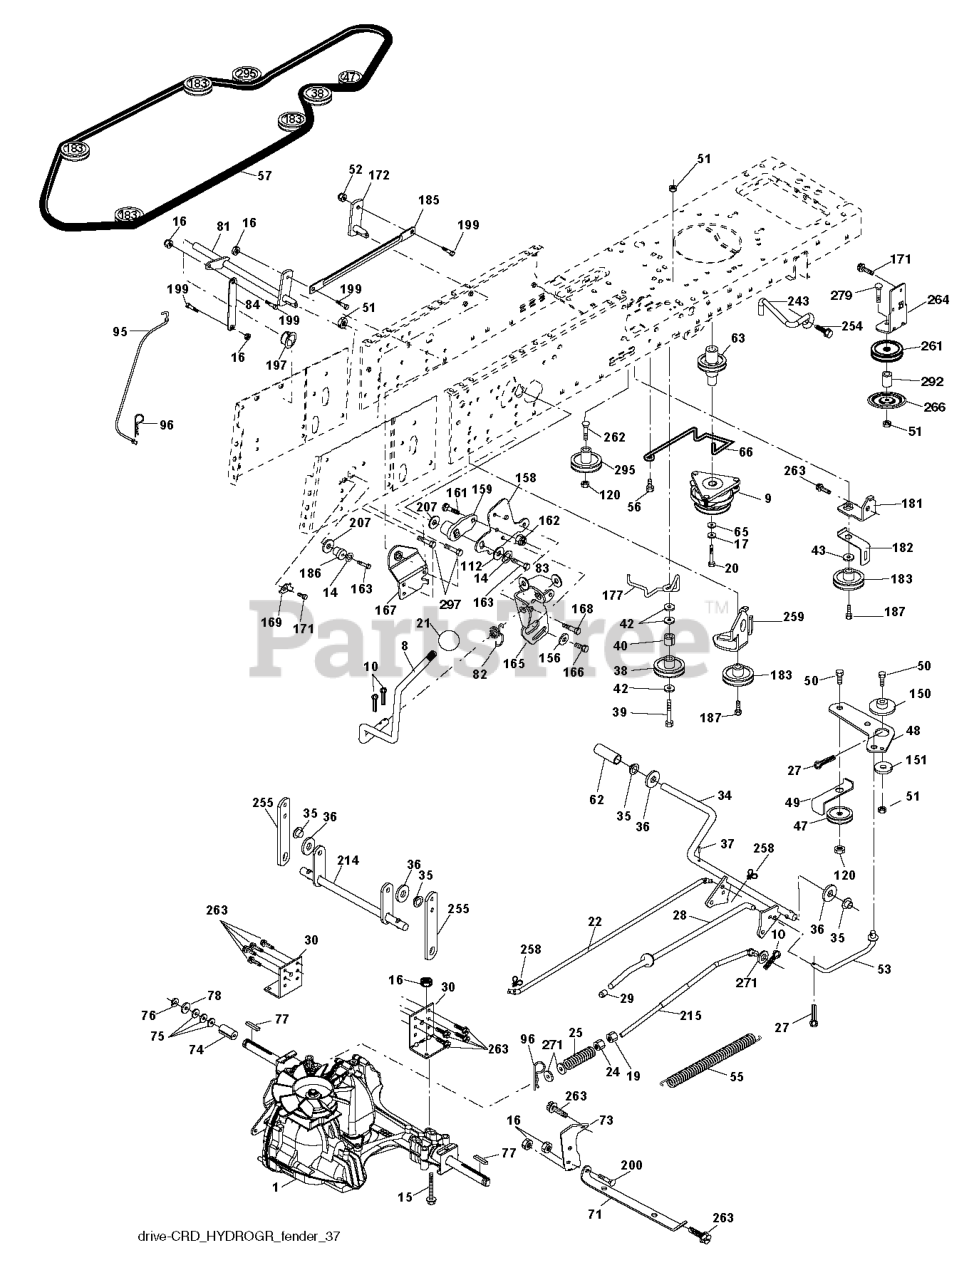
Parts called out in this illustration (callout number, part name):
8	ROD SHIFT FENDER ADJUST LT
9	CLUTCH.ELECTRIC.OGURA.EURO.
10	PIN COTTER
14	LOCKWASHER
15	BOLT HEX 5/16-18 GR 5
16	NUT.71038.31-18.HEX.NYLOCK
19	NUT
20	BOLT HEX 7/16-20X4-1/4"
21	KNOB.DUCKHEAD.1/2
22	ROD
24	NUT
25	SPRING BRAKE ROD
27	COTTER PIN
28	ROD, PARKING BRAKE
29	PLUNGER CAP
30	BRKT, TRNSXLE MNT 20"
34	SHAFT, FOOT PEDAL
35	BEARING.NYLON
36	WASHER LT
37	DRIVE PIN
38	PULLEY.FLAT
42	WASHER
43	WASHER T
47	IDLER PULLEY
48	BELLCRANK, CLUTCH
49	RETAIN BELT
50	BOLT.3/8-16X1.50
52	LOCKNUT
53	LINK.CLUTCH.7.66.2005
55	SPRING, RETURN LT
56	SCREW.3/8-16
57	V-BELT 113"
62	PEDAL COVER T
63	PULLEY.ENGINE.CVX.LT
65	LOCKWASHER
66	KEEPER BELT ENGINE
71	STRAP TORQUE LH HYDRO
73	STRAP TORQUE RH HYDRO
74	SPACER AXLE
77	SQUARE KEY
81	ASM.CROSS.SHAFT.REAR.CRD.0510
82	SHIFT SPRING
83	WASHER
84	LINK.PNT.TRANSAXLE.0510.CRD
95	LINK
96	RETAINER M
112	WASHER LT
120	NUT LOCK FLG 3/8-16 UNC
150	BUSHING.BELLCRANK.GRD.DR
151	WASHER 12/32X2X10GA
156	WASHER.SRRTD.5/16
158	BRACKET.SHIFT.MOUNT
159	RB HUB.SHIFT
161	BOLT
162	NUT.CROWNLOCK.1/4
163	BOLT
165	BRACKET.PIVOT.LEVER
166	CAPSCREW.HXHD.FLG.5/16-18X.625
167	BRACKET.SUPT.SHIFT.CRD
168	BOLT.SHOULDER.5/16-18X
169	PLATE.FASTENING.CROSS.SHAFT
171	SCREW LT
172	LINK
181	BRACKET
182	BELT GUIDE
183	PULLEY.V-IDLER.
185	LINK
186	HUB.TAPERED.ROUND.CRD
187	BOLT.5/16-18X1.25
197	NYLINER SNAP 5/8" ID
199	BOLT SHOULDER 5/16-18 UNC
200	BOLT
207	WASHER NYL
214	LEVER
215	ROD
243	BRACKET, ANTI-ROTATION
252	WASHER
254	SCREW 3/8-16X1
255	SHAFT
258	CLIP RETAINER
259	BRACKET
261	FLAT IDLER PULLEY
263	SCREW, 3/8-16X3/4
264	BRACKET.IDLER
266	PROTECTOR
279	BOLT
292	SPACER
295	PULLEY IDLER COMPOSITE
297	SCREW LT.3/8-46X5/8
